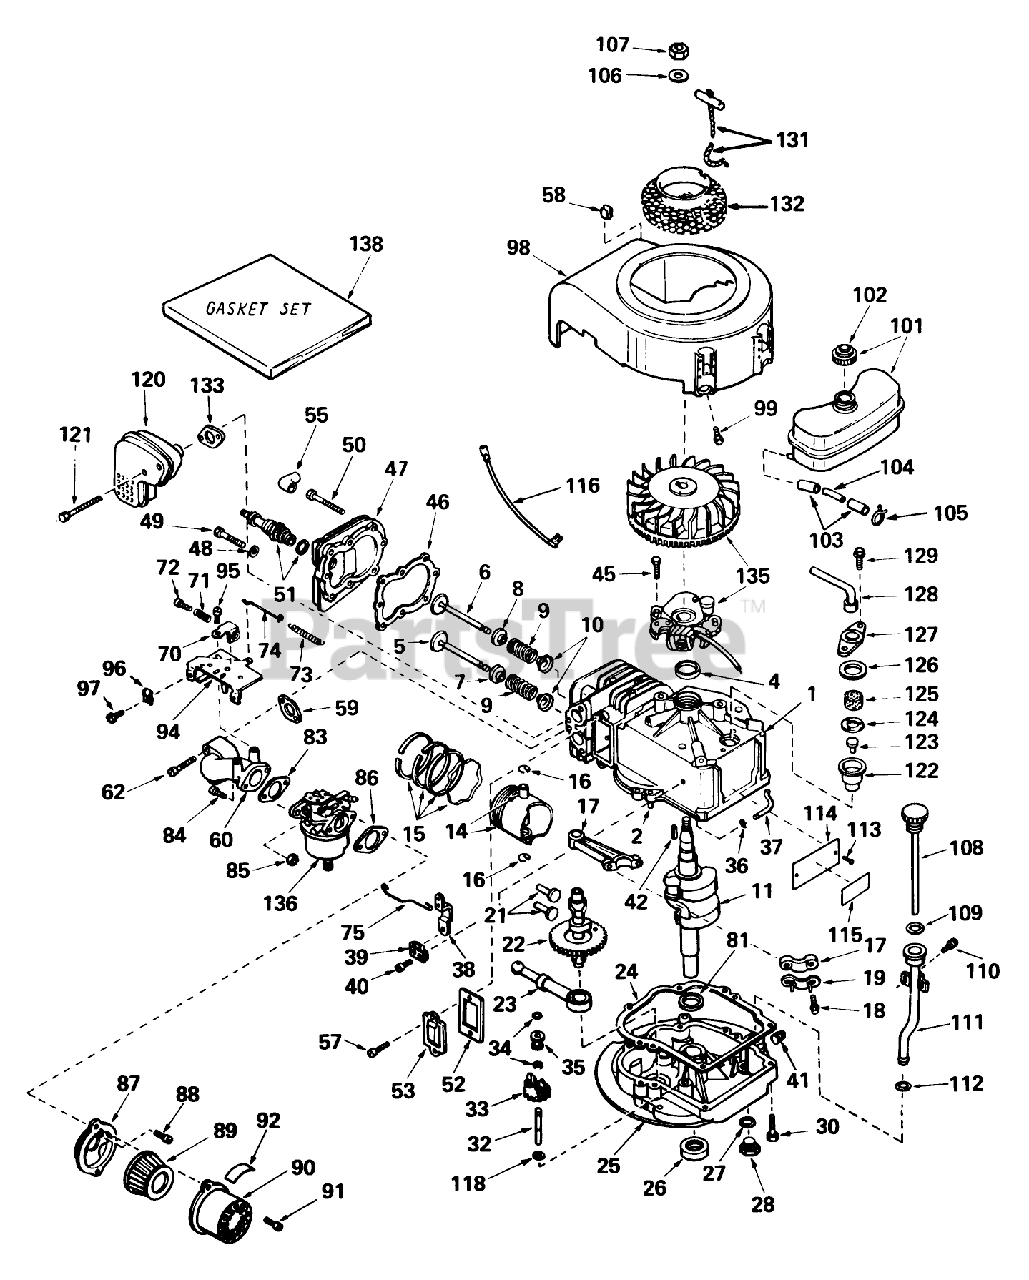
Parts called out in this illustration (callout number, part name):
1	Cylinder Assy. (Incl. Nos. 2 4)
2	Pin-Dowel
4	Seal-Oil
5	Valve, Intake (Standard) (Incl. Nos. 7, 9 10)
5	Valve, Intake (1/32" Oversize) (Incl. Nos. 7, 9 10)
6	Valve, Exhaust (Standard) (Incl. Nos. 8, 9 10)
6	Valve, Exhaust (1/32" Oversize) (Incl. Nos. 8, 9 10)
7	Cap-Upper Valve Spring
8	Cap, Upper Valve Spg (Exhaust)
9	Spring-Valve
10	Cap-Valve, Spring
11	Crankshaft Assy.
14	Piston Pin Assy. (Standard) (Incl. 2 of No. 16)
14	Piston Pin Assy. (.010 Oversize) (Incl. 2 of No. 16)
14	Piston Pin Assy. (.020 Oversize) (Incl. 2 of No. 16)
15	Ring Set-Piston Std.
15	Ring Set-Piston .010 oversize
15	Ring Set-Piston .020 oversize
16	Ring-Retaining, Piston Pin
17	Rod Assy., Connecting (Incl. Nos. 18 19)
18	Connecting Rod Bolt
19	Plate Lock
21	Lifter-Valve
22	Camshaft (Compr. Release)
23	Oil Pump ASM
24	Gasket, Mounting
25	Flange Assy., Mounting (Incl. Nos. 26, 27, 28 32)
26	Seal-Oil
27	Gasket-Oil Drain
28	Plug, Drain
30	Screw (1/4-20 x 1-1/4)
32	Shaft-Governor
33	Governor Gear ASM
34	Ring-Retaining
35	Spool-Governor
36	Washer-Flat
37	Rod, Governor (Incl. No. 36)
38	Governor Lever
39	Clamp-Lever, Governor
40	Screw
41	Plug-Pipe
42	Key Flywheel
45	Screw
46	Oil Fill Tube
47	Head Cylinder
48	Washer
49	Screw
50	Screw Hex Hd. Cap
51	Plug, Spark (J17LM or equiv.)
52	Gasket-Breather
53	Cover-Valve
55	Cover-Spark Plug
57	Screw
58	51004 GIL ROTARY TI
59	Gasket, Intake
60	Pipe, Intake
62	Screw, Fil. Slotted Hd.Sems
70	Brachet, Control
71	Spring
72	Screw, Hex Hd.
73	Spring, Governor
74	Link Governor Spring
75	Link Governor
81	Washer-Thrust
83	Gasket
85	Nut and Lock Washer (1/4-28)
86	Gasket
87	Bracket
88	Screw (10-32 x 1/2)
89	Element
90	Body
91	Screw
92	Decal
94	Control Assy., Speed
95	Screw (10-24 x 9/16)
96	Conduit
97	Screw (10-32 x 3/8)
98	61718/GIL1605A/95-5
99	Screw (1/4-20x19/32)
101	Tank Assy., Fuel (Incl. No. 102)
102	Cap, Fuel
103	Line-Fuel (8.62)
104	Line, Fuel
105	Clamp-Line, Fuel
106	Washer-Spring
107	Hex Nut
108	Dipstick, Assy., Oil (Incl. No.109)
109	O-Ring
110	Screw (10-32 x 1/2)
111	Tube Assy., Oil Fill
112	O-Ring
113	Stud
114	IDENTIFICATION PLATE
115	480B GIL SNWTHWR O/
116	SPOOL RETAINER (10-PK)
118	Washer-Flat
120	Muffler
121	Screw-Fil. Hd.
122	Body Breather Tube
123	Valve Check
124	2000A37 WIZARD ROTA
125	Element-Breather
126	Gasket-Breather
127	Cover Breather
128	Tube, Breather
129	Screw, Hex Hd. w/Conical
131	Rope Assy., Starter
132	61719/GIL1607A,VARI
133	Gasket-Exhaust
135	Magneto
136	Carburetor
138	Gasket Set
